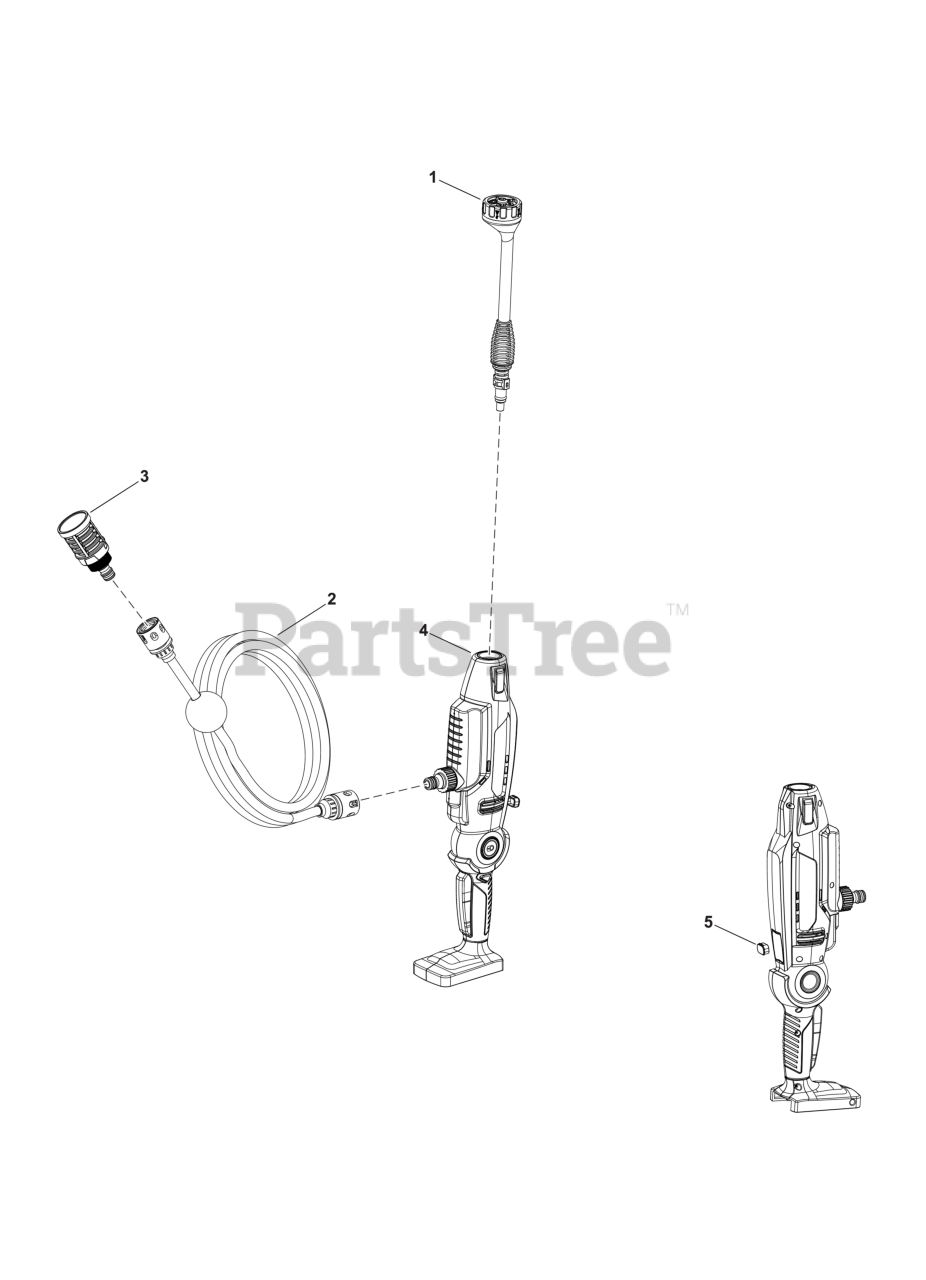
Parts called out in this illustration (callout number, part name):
1	SPRAY NOZZE, 5-IN-1
2	HOSE, GUN PRESSURE WASHER, 6M
3	ASSEMBLY, INTAKE FILTER
4	MAIN BODY ASSEMBLY
5	TOP INSERT
